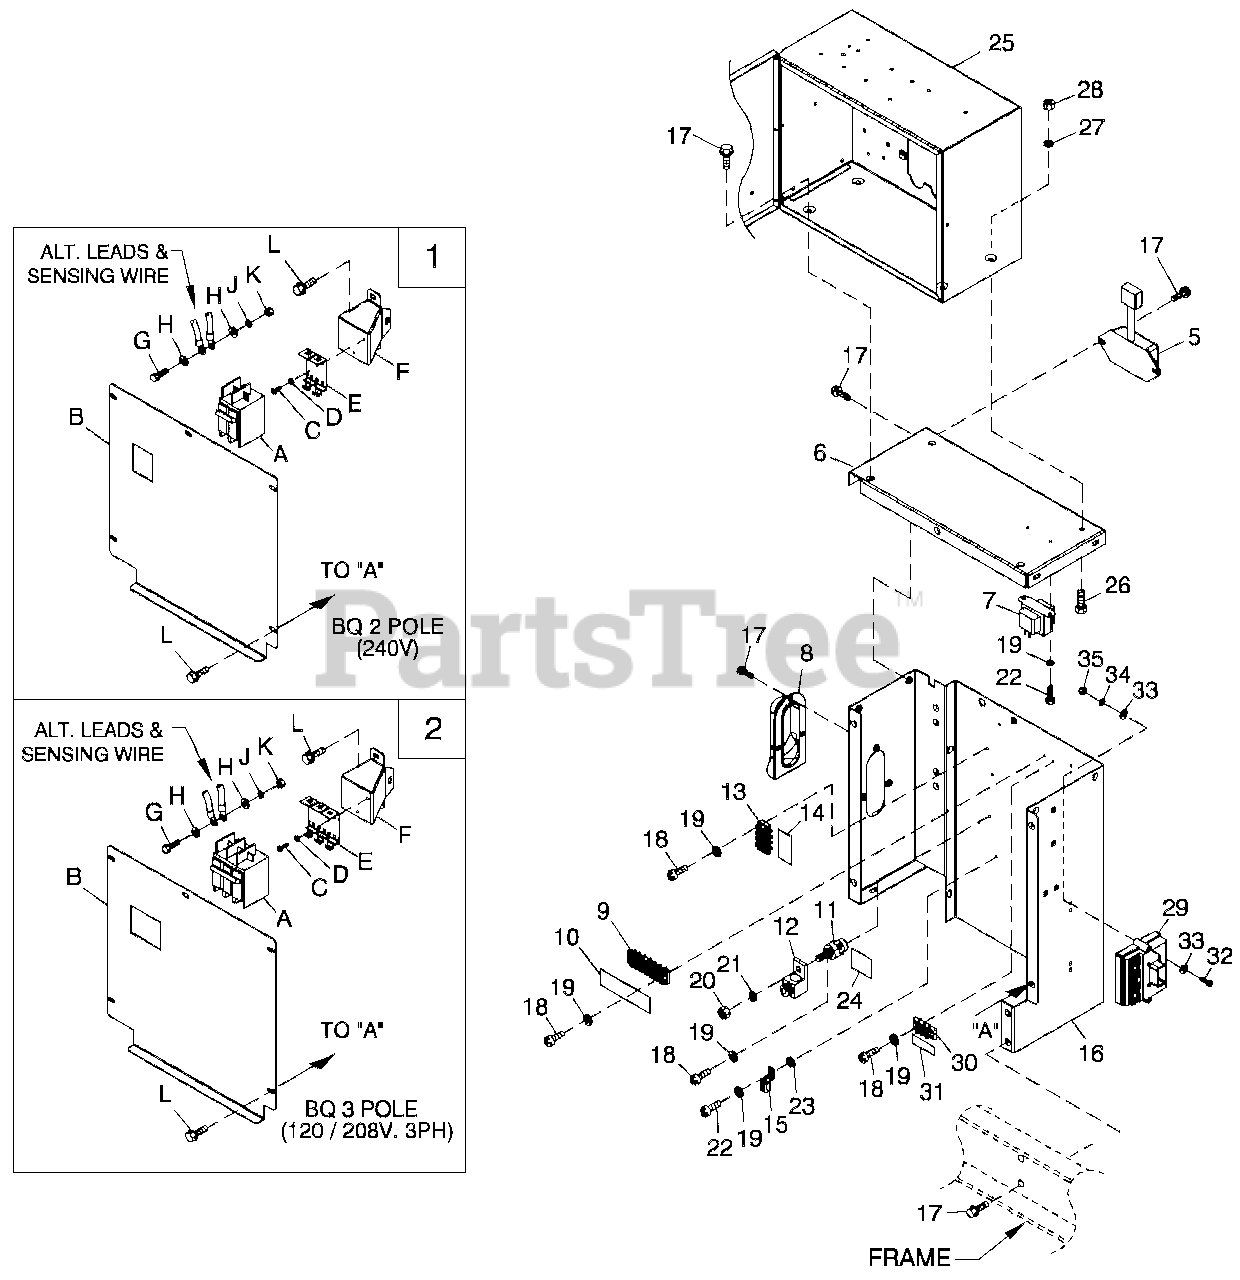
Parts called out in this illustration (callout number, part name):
5	REGULATOR - DC ALT (1.6L ONLY)
6	CONBOX TOP PANEL SUPPORT
7	XFMR 208 TO 16V 6VA (208V. ONLY)
8	COVER BELL HOUSING CONBOX
9	BLOCK TERM 20A 6 X 6 X 1100V
10	DECAL RTS CUSTOMER CONNECTION
11	JUNCTION BLOCK 3/8-16
12	LUG SLDLSS 350-#6X13/32 AL/CU
13	BLOCK TERM 20A 6 X 3 X 1100V
14	DECAL CHARGER POWER 120VAC
15	LUG SLDLSS #6-14 X 13/64 CU
16	CONBOX BACK & SIDES 1.6L
17	SCREW HWHTF M6-1.0 X 16
18	SCREW PHTT M4-0.7 X 16 ZYC
19	WASHER LOCK #8-M4
20	NUT HEX 3/8-16 STEEL
21	WASHER LOCK 3/8
22	SCREW PHTT M4-0.7 X 8 ZYC
23	WASHER SHAKEPROOF EXT #10 STL
24	DECAL NEUTRAL
25	ASSY R-200 3600 1.6L
26	SCREW HHC M6-1.0 X 16 G8.8
27	WASHER LOCK M6-1/4
28	NUT HEX M6 X 1.0 G8 YEL CHR
29	ASSY PCB IGN MOD 2.4L NO-TURBO (2.4L ONLY)
30	BLOCK TERM 20A 2 X 6 X 1100V
31	DECAL GTS CUSTOMER CONNECTION
32	SCREW PPHM #10/32 X 2 (2.4L ONLY)
33	WASHER FLAT #10 ZINC (2.4L ONLY)
34	WASHER LOCK #10 (2.4L ONLY)
35	NUT HEX #10-32 STEEL (2.4L ONLY)
A	CB 0090A 2P 240V S BQ2 LL
B	CB COVER 20-25K 1P (BQ2)
C	SCREW PHTT M4-0.7 X 8 ZYC
D	WASHER LOCK #8-M4
E	BRKT CB MTG BACK
F	CIRCUIT BREAKER SUPPORT (BQ)
G	SCREW HHC M5-0.8 X 20 G8.8
H	WASHER FLAT #10 ZINC
J	WASHER LOCK M5
K	NUT HEX M5-0.8 G8 CLEAR ZINC
L	SCREW HWHTF M6-1.0 X 16
A	CB 0070A 3P 240V S BQ3 LL
B	CB COVER 20-25K 3P (BQ3)
